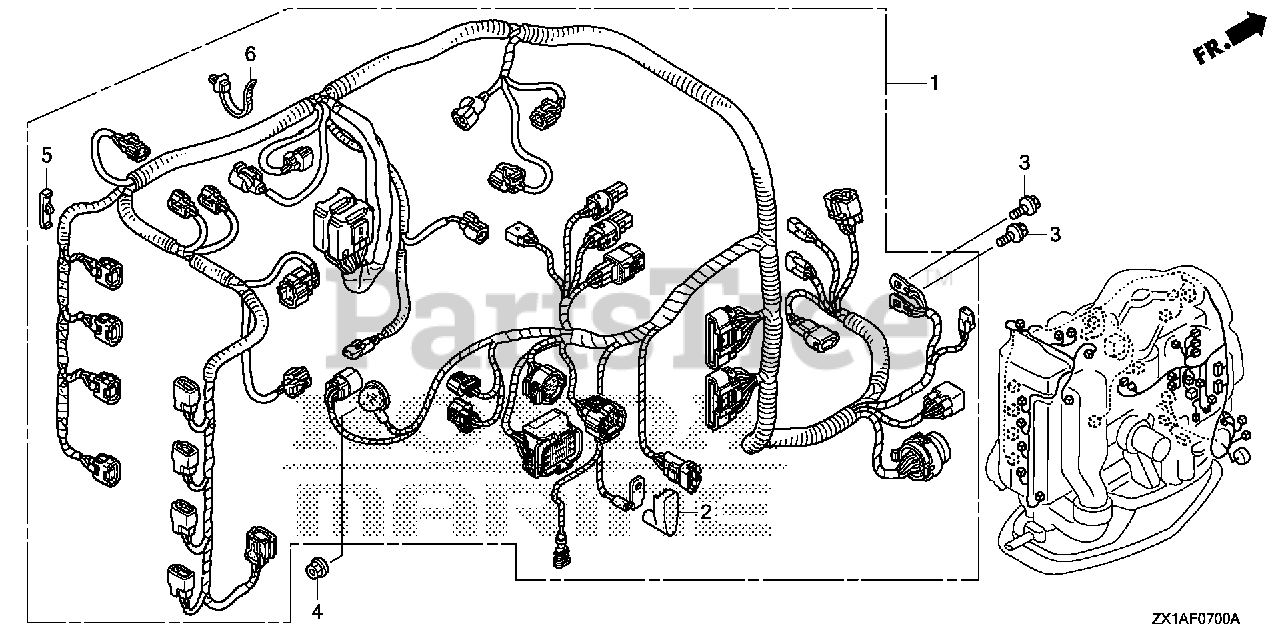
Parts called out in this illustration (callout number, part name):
1	WIRE HARNESS ASSY., MAIN
1	WIRE HARNESS, MAIN
2	COVER B, TERMINAL (L)
3	BOLT, FLANGE (6X12)
4	NUT-WASHER (6MM)
5	CLIP, WIRE HARNESS
6	CLIP, HARNESS BAND (145MM) (BLACK)
